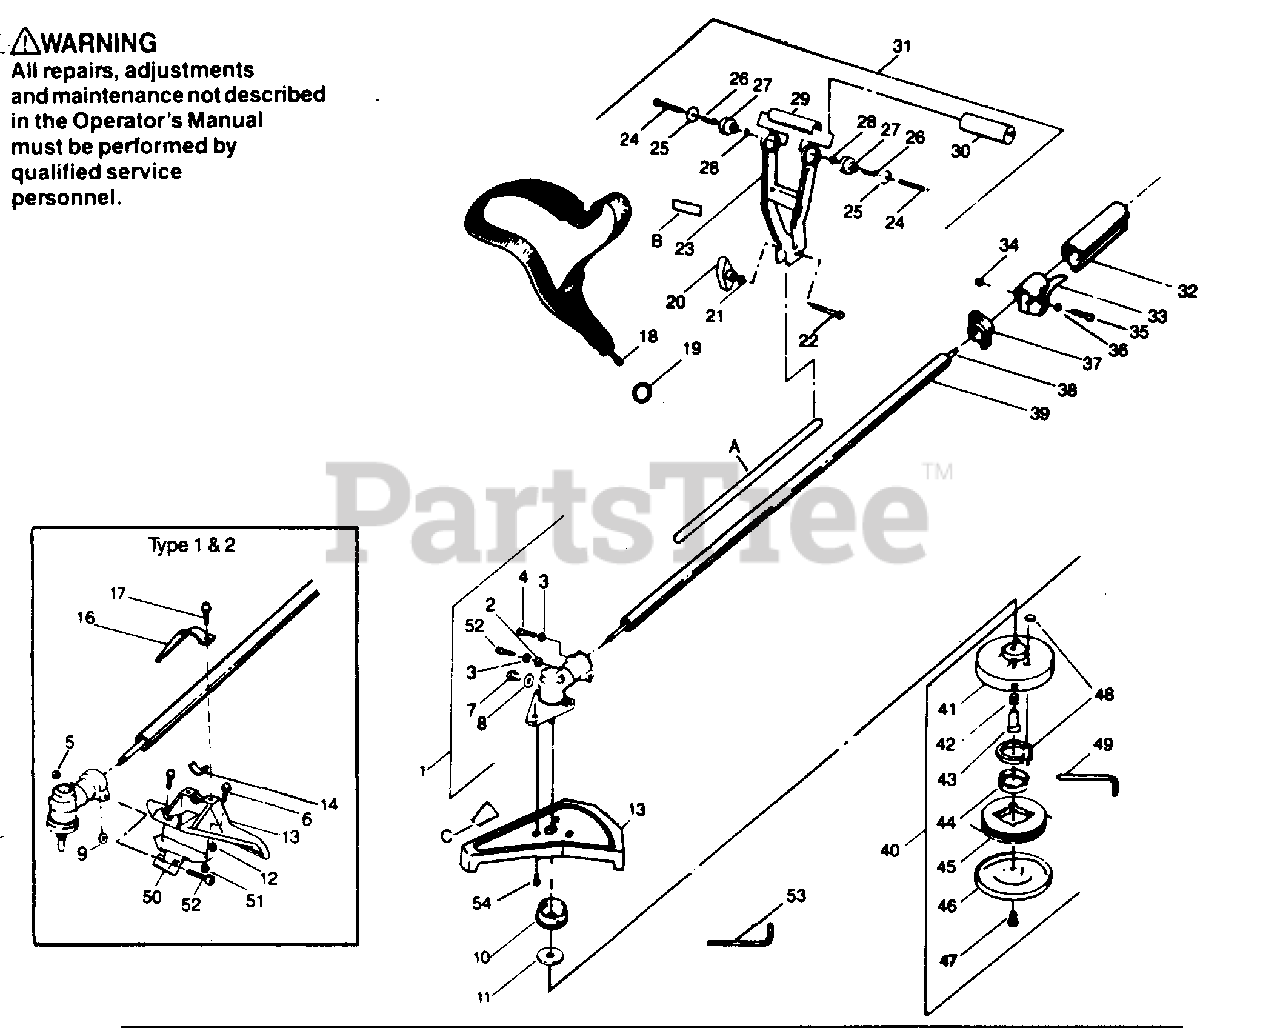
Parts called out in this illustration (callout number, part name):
1	Type 1 & 2
2	Lockwasher - Type 2
2	Washer Type 3
3	Lockwasher
4	Screw-5 x 12.5 MM-Soc. Hd Gear Box-Index
5	Nut-5mm Gear Box-Pinch Clamp-Type 2 only
6	Screw-Sems-6 x 16mm-Type 2 only
7	Type 1 & 2
8	Type 1 & 2
9	Washer-Spacer-Gear Box - Type 1 & 2
10	Adaptor-Upper
11	Adaptor-Lower
12	Nut-6mm-Shield Type 1 & 2
14	Spacer-Shield-Type 1 & 2
16	Bracket-Shield
17	Screw-6x20mm-Shield
18	Shoulder Strap
19	Key Ring-Shoulder Strap
20	Knob-Handle
21	Washer-1/4"-Handle
22	Screw-#1/4-20x1-3/4" Handle
23	Handle Antivibe
24	Screw-#12-11x2"-Isolator Handle
25	Cup-Isolator-Handle
26	Spacer-Isolator Handle
27	Isolator-Handle
28	Washer-Flat-Handle
29	Center-Section-Handle
30	Cushion-Handle
31	Ass'y-Antivibe Handle (incl. #23-30)
32	Grip-Drive Shaft Hsg.
33	Throttle Control Ass'y.
34	Lock Nut-Hex-5mm-Throttle Control
35	Screw-5x25mm Phil.
36	Washer-Throttle Control Throttle Control
37	Clamp-Shoulder Strap
38	Type 2 & 3
39	Type 2 & 3
40	Cutting Head Assembly (incl. #41-49)
41	Hub-Cutting Head
42	Line Saver-Cutting Head
43	Drive Adaptor Cutting Head
44	Spring-Cutting Head
45	Spool w/Line-Cutting Head
46	Cover-Cutting Head
47	Screw-#3/8-16x7/8"-Cover
48	Release Button (incl. Lock Ring)
49	Allen Wrench-Cutting Head
50	Bracket-Lower-Splash Deflector-Type 2 only
51	Nut-Hex-6mm-Type 2 only
52	Type 1 & 3 (5x25mm)
52	Type 2 (5x35 mm)
53	Wrench-Hex-4mm
54	Screw-Type 3
B	Decal-Antivibe
C	Decal-Warning Shield
